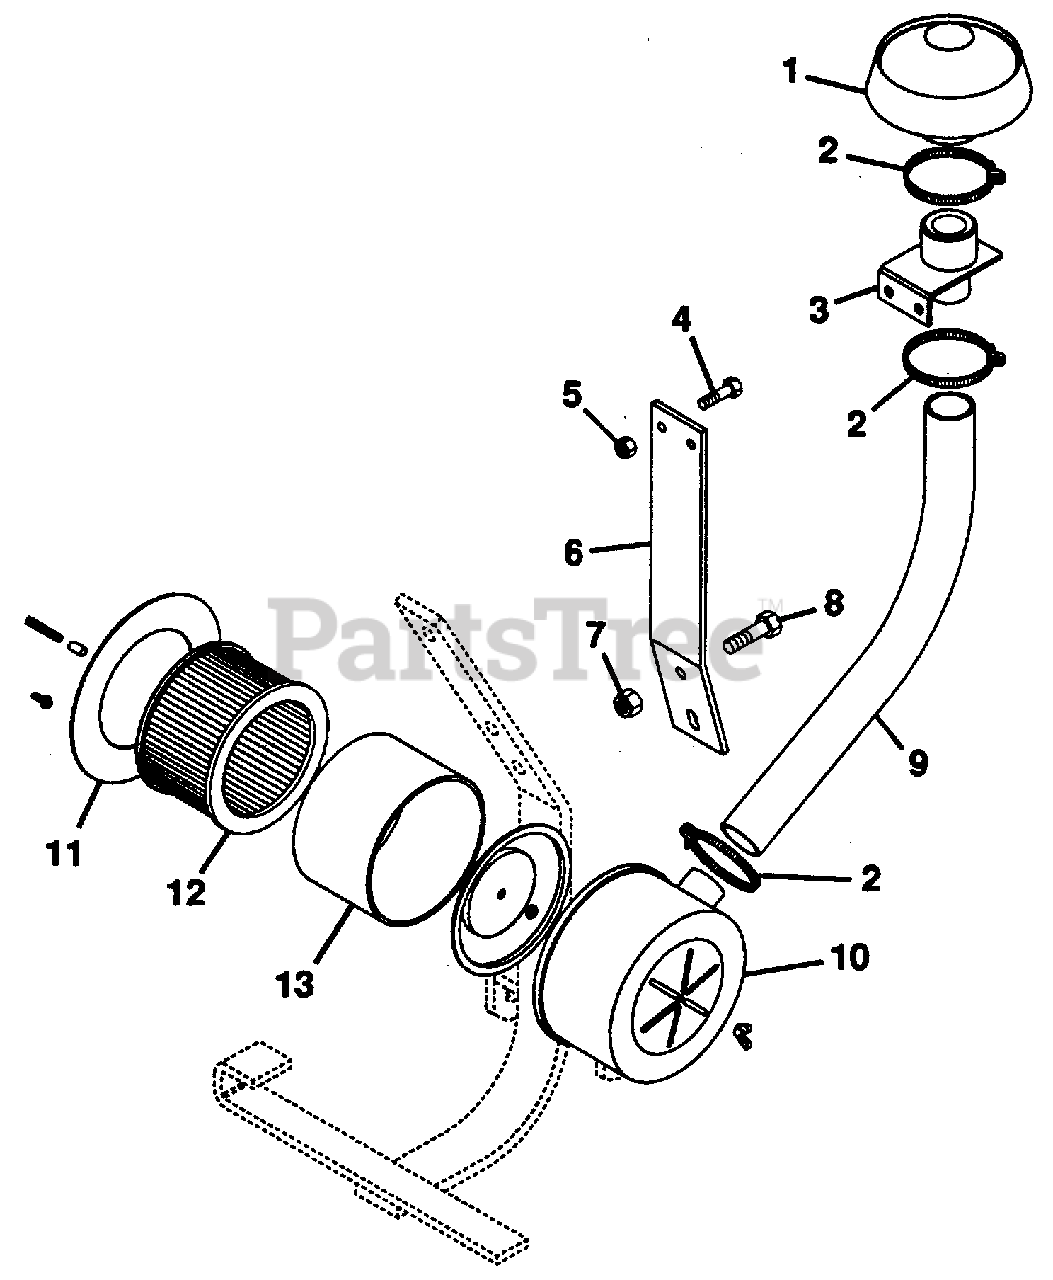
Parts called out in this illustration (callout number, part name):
1	Hood, Air Inlet
2	Clamp, 2.25 Dia. Hose
3	Weldment
4	Bolt, Hex 3/8-16x1.12
5	Nut, Lock 3/8-16
6	Bracket
7	Nut, Lock 1/2-13
8	Bolt, Hex 1/2-13x1.50
9	Hose, Air Cleaner
10	Cover, Air Cleaner
11	Gasket
12	Element, Air Filter
13	Element, Pre-Cleaner
NS	Clamp, Muffler
